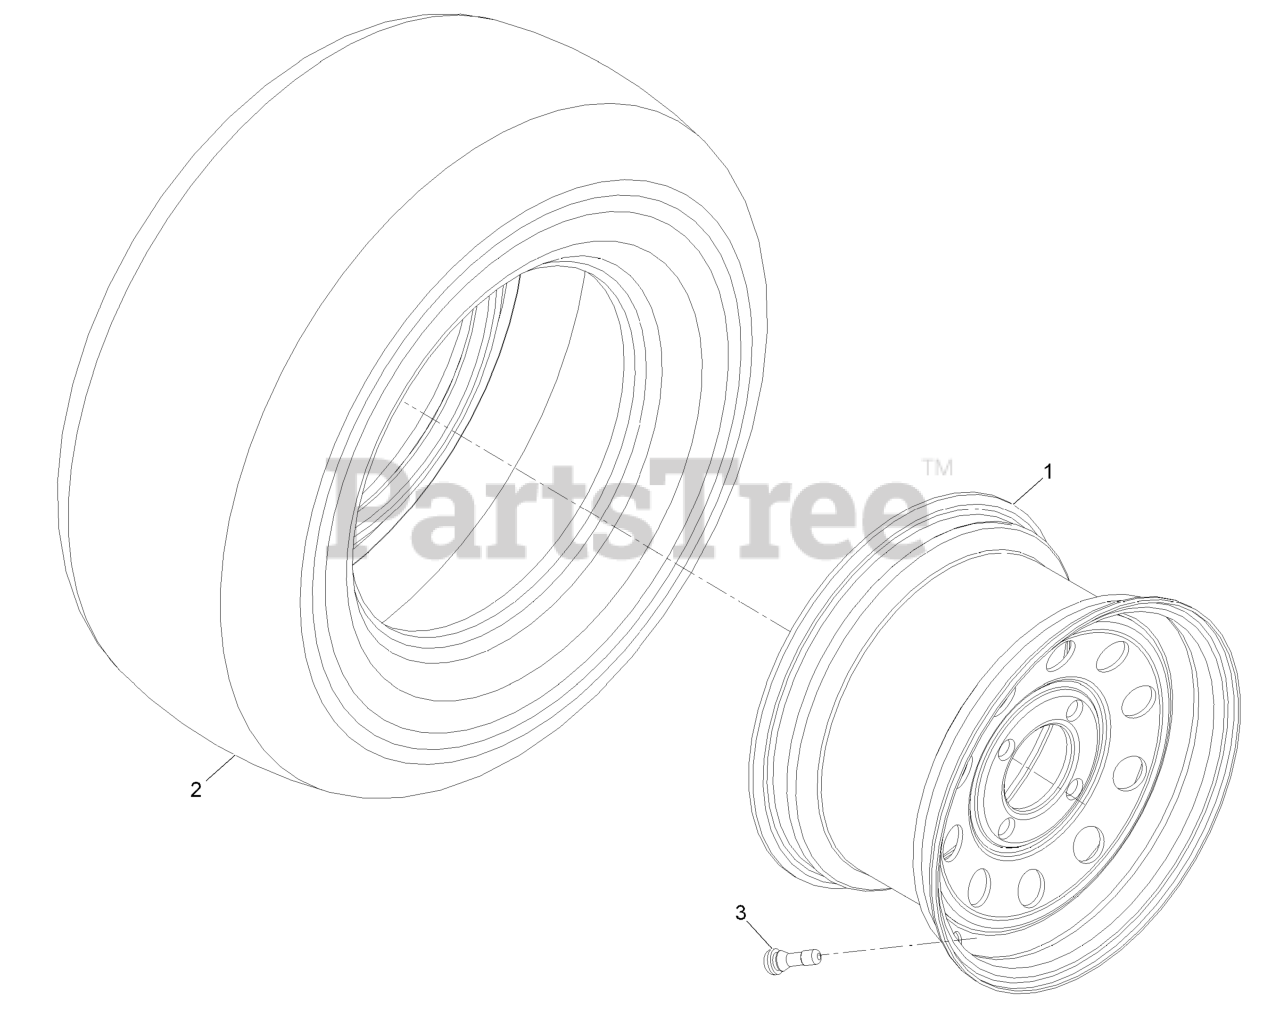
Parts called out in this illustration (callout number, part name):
1	RIM ASM
2	TIRE-STANDARD
3	Stem-Valve
